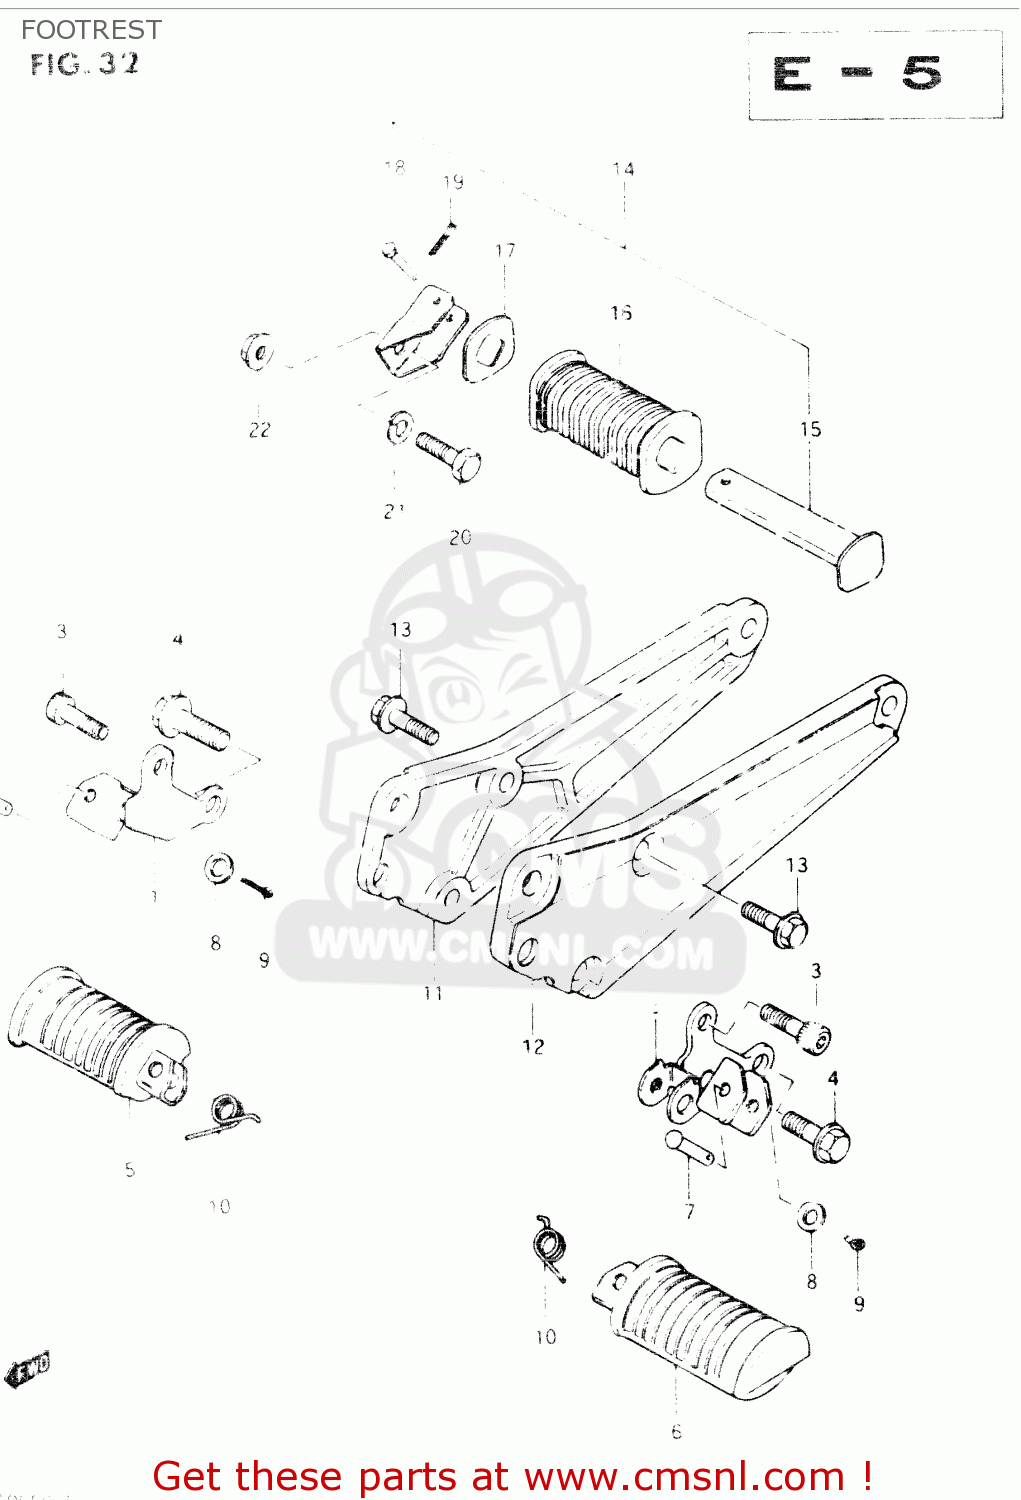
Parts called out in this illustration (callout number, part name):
1	BAR,FR FOOTREST,R
2	BAR,FRONT FOOTREST,LEFT
3	BOLT
4	BOLT ,10X25
5	RUBBER,PILLION FOOTREST,R
6	RUBBER,PILLION FOOTREST,L
7	PIN
8	WASHER
9	PIN 20X20
10	SPRING
11	BRACKET,MUFFLER,RIGHT
12	BRACKET,MUFFLER,LEFT
13	BOLT ,10X25
14	FOOTREST ASSY,PILLION,R
15	BAR,REAR FOOTREST,LEFT
16	RUBBER,PILLION FOOTREST
17	WASHER,FOOTREST RUBBER
18	PIN
19	PIN 20X20
20	BOLT,M10X1.25X
21	LOCK WASHER
22	NUT
